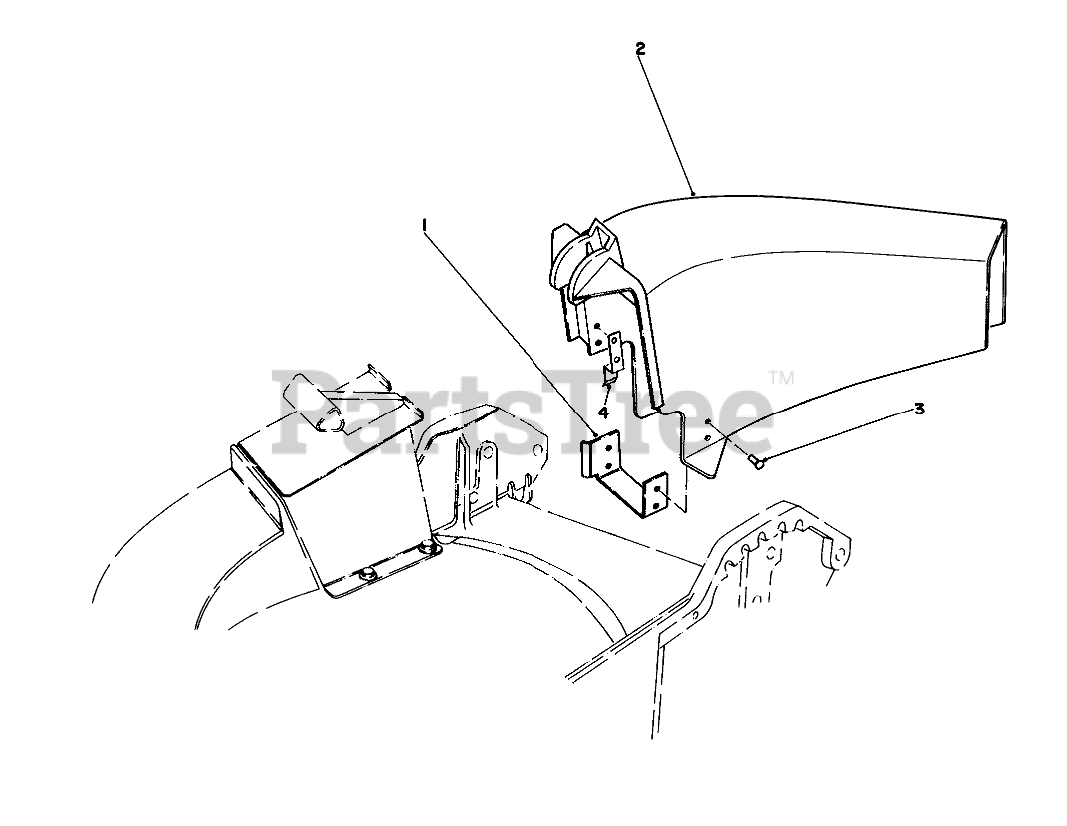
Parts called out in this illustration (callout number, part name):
1	CHUTE BRACKET
2	Chute Discharae
3	RIVET
4	CHUTE TAB
